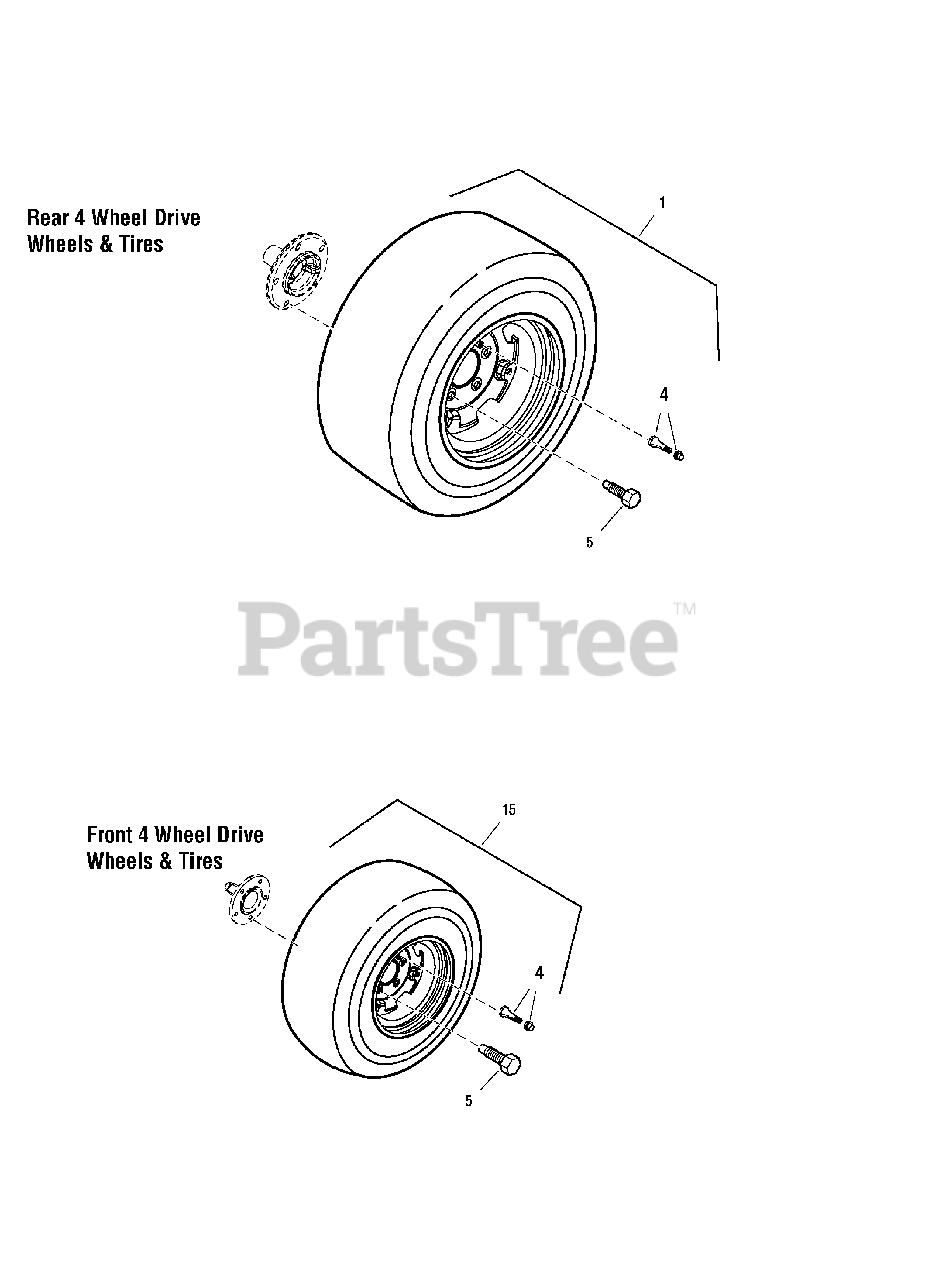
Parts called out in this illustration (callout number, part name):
1	WHEEL & TIRE ASSEMBLY, Turf Tires, Rear
1	WHEEL & TIRE ASSEMBLY, HD Field Trac, Rear
2	TIRE, Turf Tire, 26 x 12-12
3	WHEEL, Turf Tire, Rear 8.5 x 12
4	VALVE STEM & CAP
5	HUB BOLT
15	WHEEL & TIRE ASSEMBLY, Turf Tires, Front, 4 Wheel Drive
15	WHEEL & TIRE ASSEMBLY, HD Field Trac, Front, 4 Wheel Drive
16	TIRE, Turf Tire, Front, 18 x 8.5-8
17	WHEEL, Turf Tire, Front, 4 Wheel Drive
